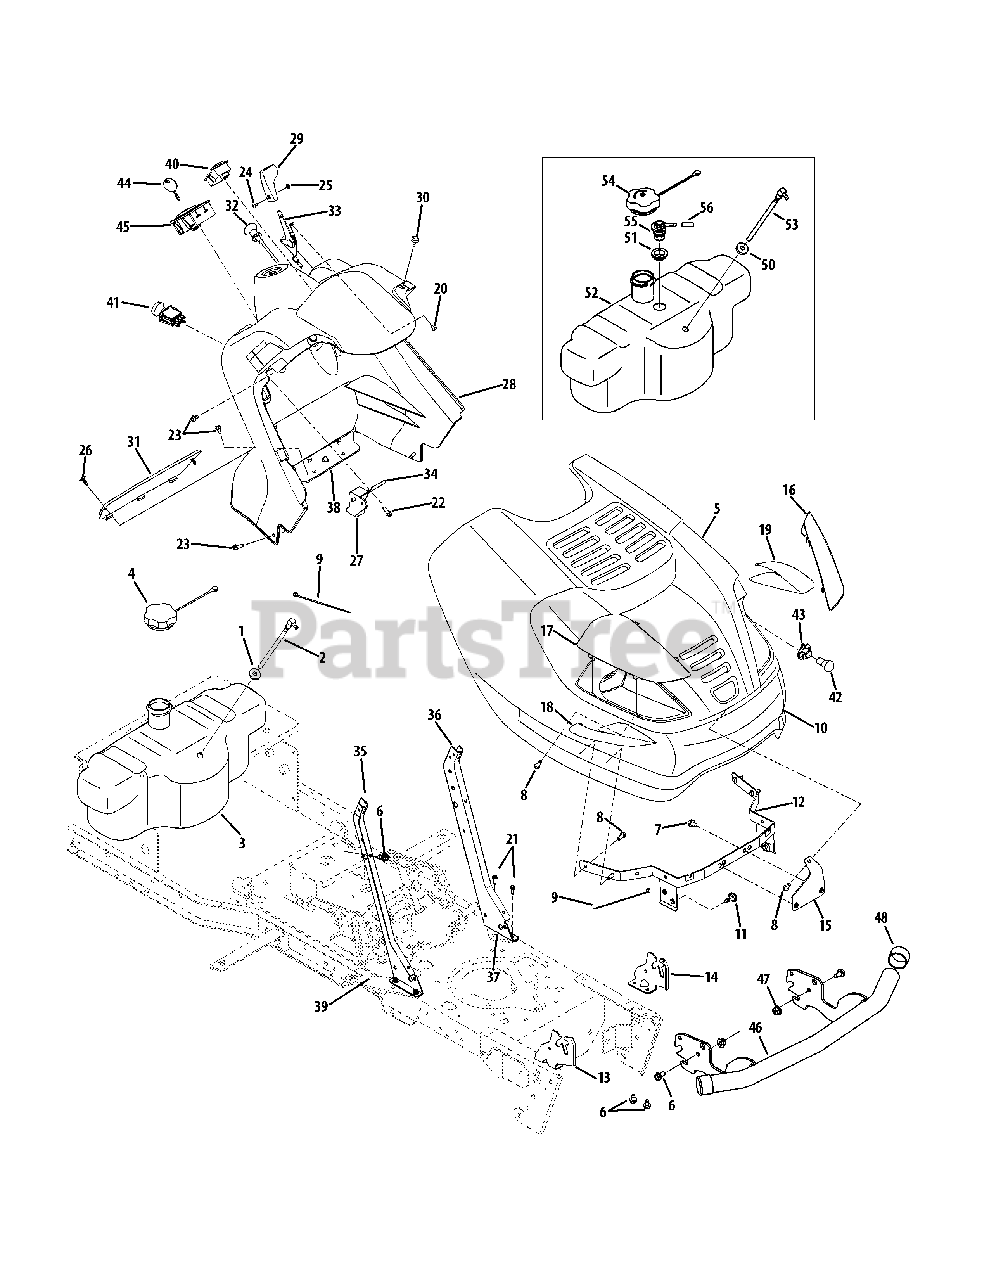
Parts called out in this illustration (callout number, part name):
1	Fuel Tank Bushing
2	Fuel Pick-Up Fitting
3	Fuel Tank
4	Fuel Cap
5	Hood Plenum
6	Hex Washer Screw, 5/16-18 x .750
7	Hex Washer Screw, 5/16-18 x .625
8	Hex Washer Screw, 1/4 Dia. x .750
9	Cable Tie, 3/16 x .05 x 7.4
11	Shoulder Screw, 5/16-18 x .43 x .29
12	Hood Pivot Bracket
13	RH Hood Pivot Bracket
14	LH Hood Pivot Bracket
15	Hood Support Bracket
18	RH Lens Label
19	LH Lens Label
20	Machine Screw, #10-24 x .375
21	Hex Washer Screw, 1/4-20 x .750
22	Hex Washer Screw, 1/4-15 x .750
23	Hex Washer Screw, 1/4-20 x .625
24	Machine Screw, #8-32 x .375
25	Hex Nut, #8-32
26	Ratchet Clip
27	Brake Lever
29	Throttle Control Knob
30	Bumper, .62 x .3
31	Accessory Net
32	Choke Control (50")
32	Choke Control (42")
33	Throttle Cable (50")
33	Throttle Cable (42")
34	Brake/Cruise Pivot Rod
35	RH Dash Support Plate
36	LH Dash Support Plate
37	LH Steering Support Bracket
38	Upper Steering Support Bracket
39	RH Steering Support Bracket
40	Hour Meter/Service Indicator
41	PTO Switch
43	Light Socket
44	Key
45	Key Switch Module (U.S.)
45	Key Switch Module (Export)
46	Bumper
47	Flange Lock Nut, 3/8-16
48	Bumper Cap
49	Shoulder Bolt
50	Fuel Tank Bushing
51	Rubber Grommet
52	Fuel Tank, 2.82 Gallon
53	Fuel Pick-Up Fitting
54	Fuel Cap
55	Fuel Rollover Valve
56	Vent Hose
